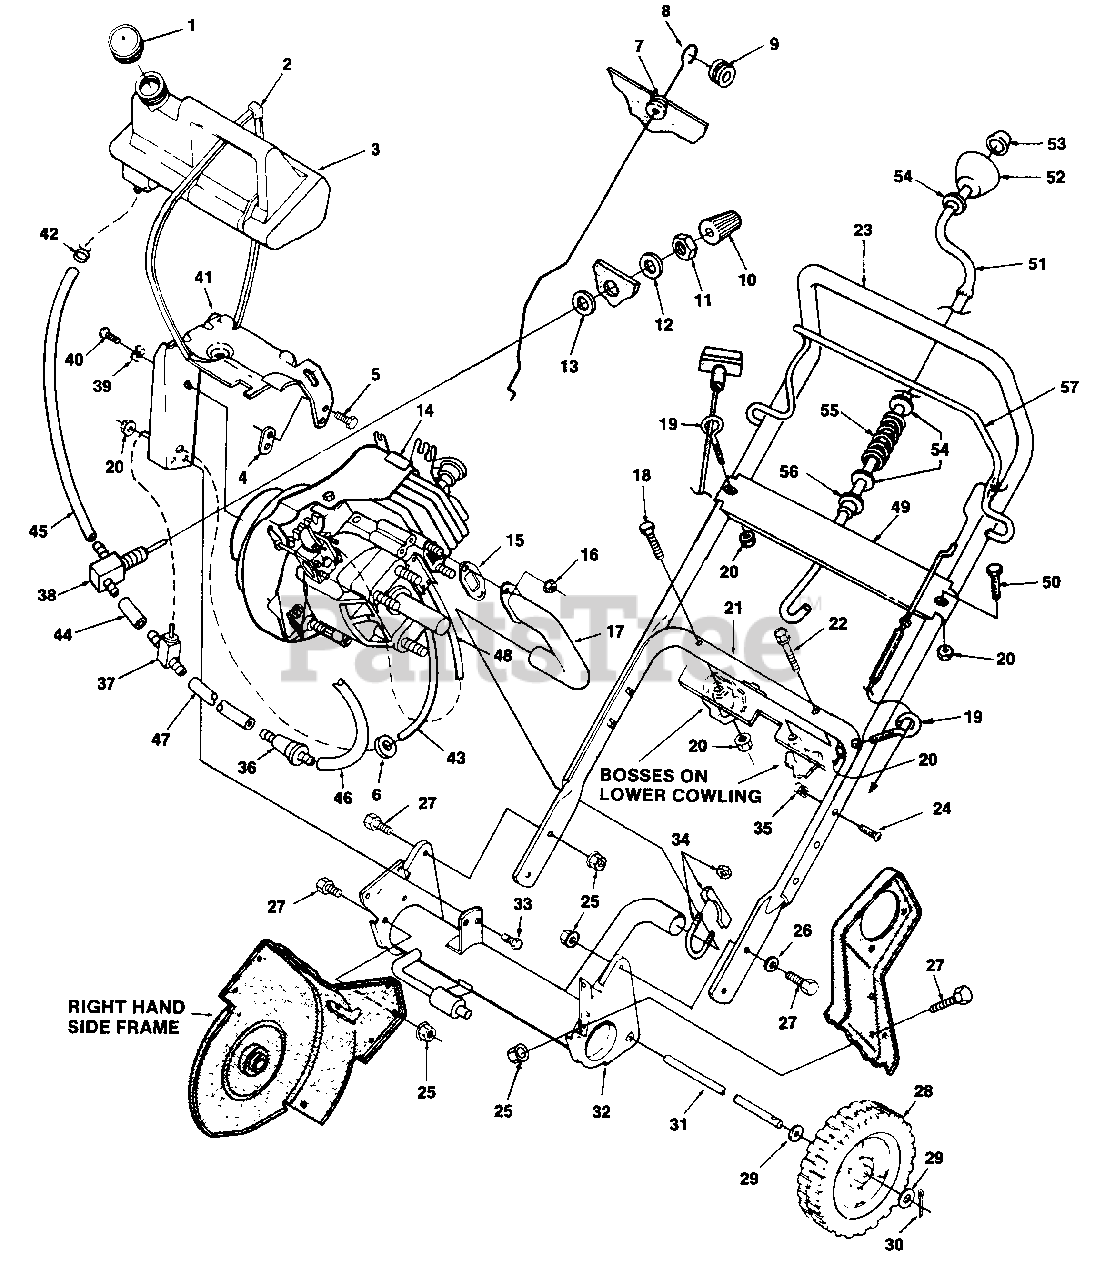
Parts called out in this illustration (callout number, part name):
2	TIE-Strap
3	TANK-Fuel
4	SPACER
5	SCREW-Thd. forming #10-24 x 3/4
8	ROD-Choke
10	KNOB-Shut-Off
11	NUT-Hex 7/16-20
12	WASHER-Lock 7/16
13	WASHER-Flat 7/16
14	SHORT BLOCK
15	GASKET-Manifold
16	NUT-Hex 5/16-18
17	MANIFOLD- Exhaust
18	SCREW-Hex hd. Cap 1/4-20 x 1 1/2
20	NUT-Flange 1/4-20
21	HANDLE-Lower
22	SCREW-Hex washer #10-16 x 1 1/2
23	HANDLE-Upper
24	SCREW-Phil Pan hd. 4/16-20 x 1 1/2
25	NUT-Flange 5/16-18
26	WASHER-Flat 5/16 (left side only)
27	SCREW-Hex 5/16-18 x 5/8
28	WHEEL & TIRE
29	WASHER-Flat
30	PIN-Cotter
31	SHAFT-Axle
33	SCREW-Hex 1/4-20 x 1/2
34	CLAMP- Muffler
36	FILTER-Fuel
37	FITTING-Fuel
39	WASHER-Lock 4/16
40	BOLT-Hex 4/16-20 x 3/8
41	BRACKET-Fuel tank
43	TUBE-Rubber 17"
44	TUBE-Rubber (cut to 1 1/2")
45	TUBE-Rubber (cut to 7 1/4")
46	TUBE-Rubber (cut to 8")
47	TUBE-Rubber (cut to 13 1/2")
48	TUBE-Rubber (cut to 11 1/4")
49	BRACE- Handle
50	BOLT- Hex hd.
51	CRANK- Chute Adj.
52	KNOB- Chute
53	CAP- Push on
54	WASHER- Flat
55	SPRING- Comp.
56	BUSHING- Nylon
57	BAIL
